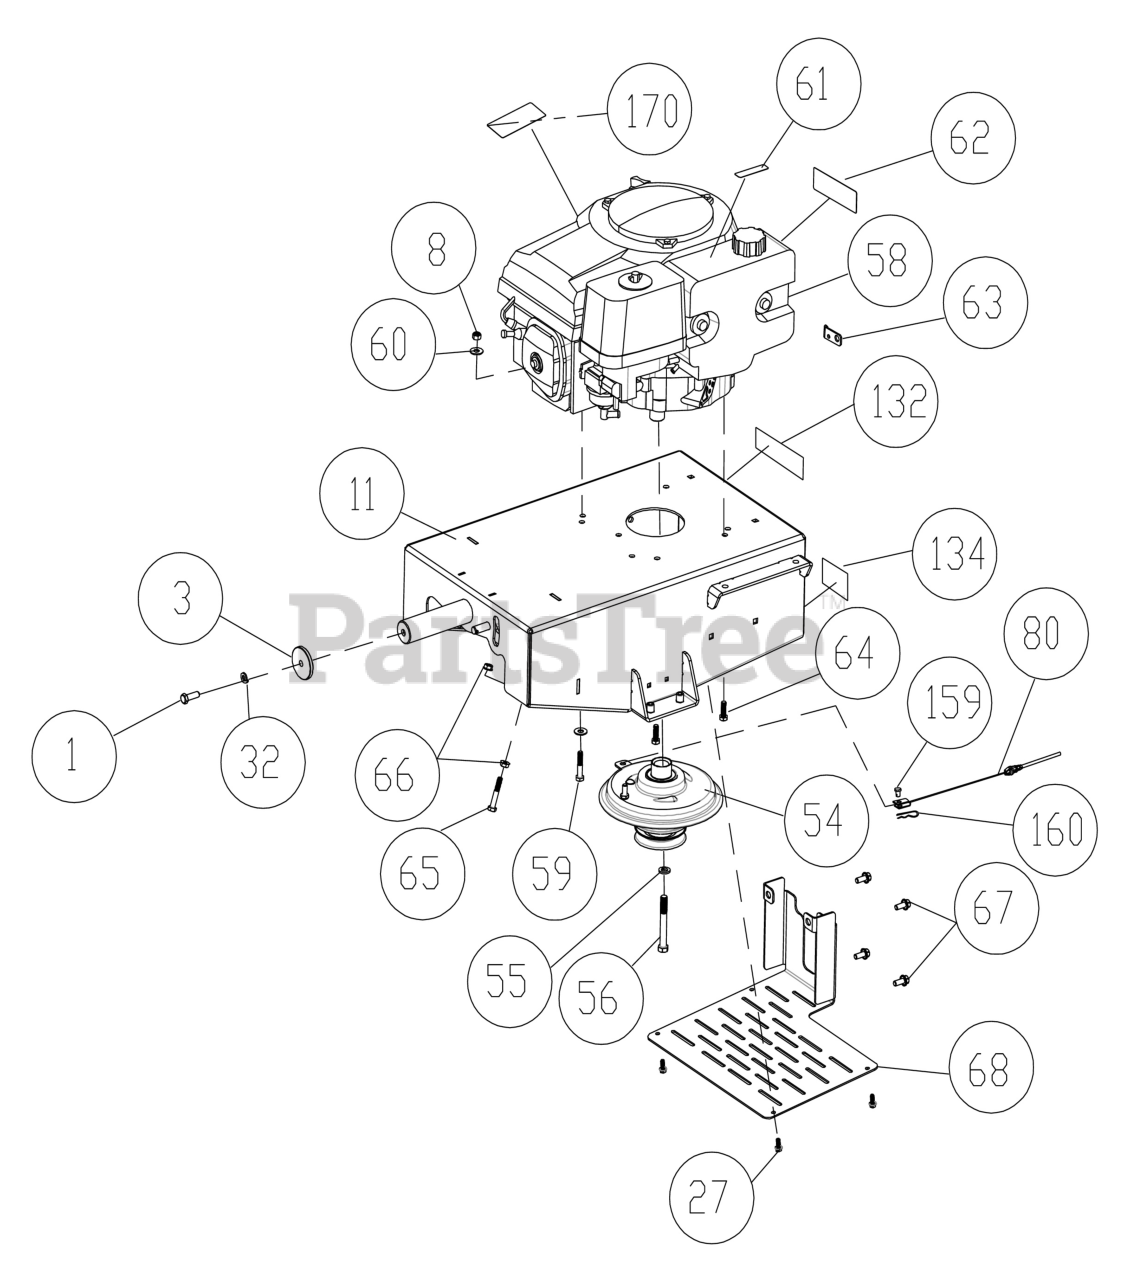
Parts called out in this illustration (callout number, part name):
1	SCREWCAP 3/8"-24 X 1" HCS GR 8
3	WASHER DECK RETAINING
8	NUT LOCK 5/16"-18 HEX Z/P
11	ENGINE BASE WA W/LABELS
27	SCREW SELF TAP 1/4"-20 X 5/8" HWH TYPE F
32	WASHER LOCK 3/8" S/T MED
54	CLUTCH BC2600 - SERVICE
55	WASHER LOCK 7/16" S/T MED
56	SCREWCAP 7/16-20 X 3 1/2 GR. 8 W/ PATCH
58	ENGINE 13HP HONDA GX390UTQA2
59	SCREWCAP 5/16"-18X1 3/4" HCS ZP
60	WASHER 5/16" FLATWASHER Z/P
61	LABEL HOT ENGINE
62	LABEL SPARK ARRESTOR
64	SCREWCAP 5/16"-24 X 1" GR.8 ZP W/PATCH
65	SCREWCAP 5/16"-18X2" HCS ZP
66	NUT FLANGE 5/16"-18 ZP
67	SER HEX WASHER FLNG SCREW 5/16"-18 X 3/4"
68	GUARD REAR HYDRO BC26
80	CABLE CLUTCH
134	LABEL SAFETY PROTECT READ MANUAL
159	PIN CLEVIS 1/4" X .75"
160	PIN CLIP HITCH 0.051 X 3/4"
